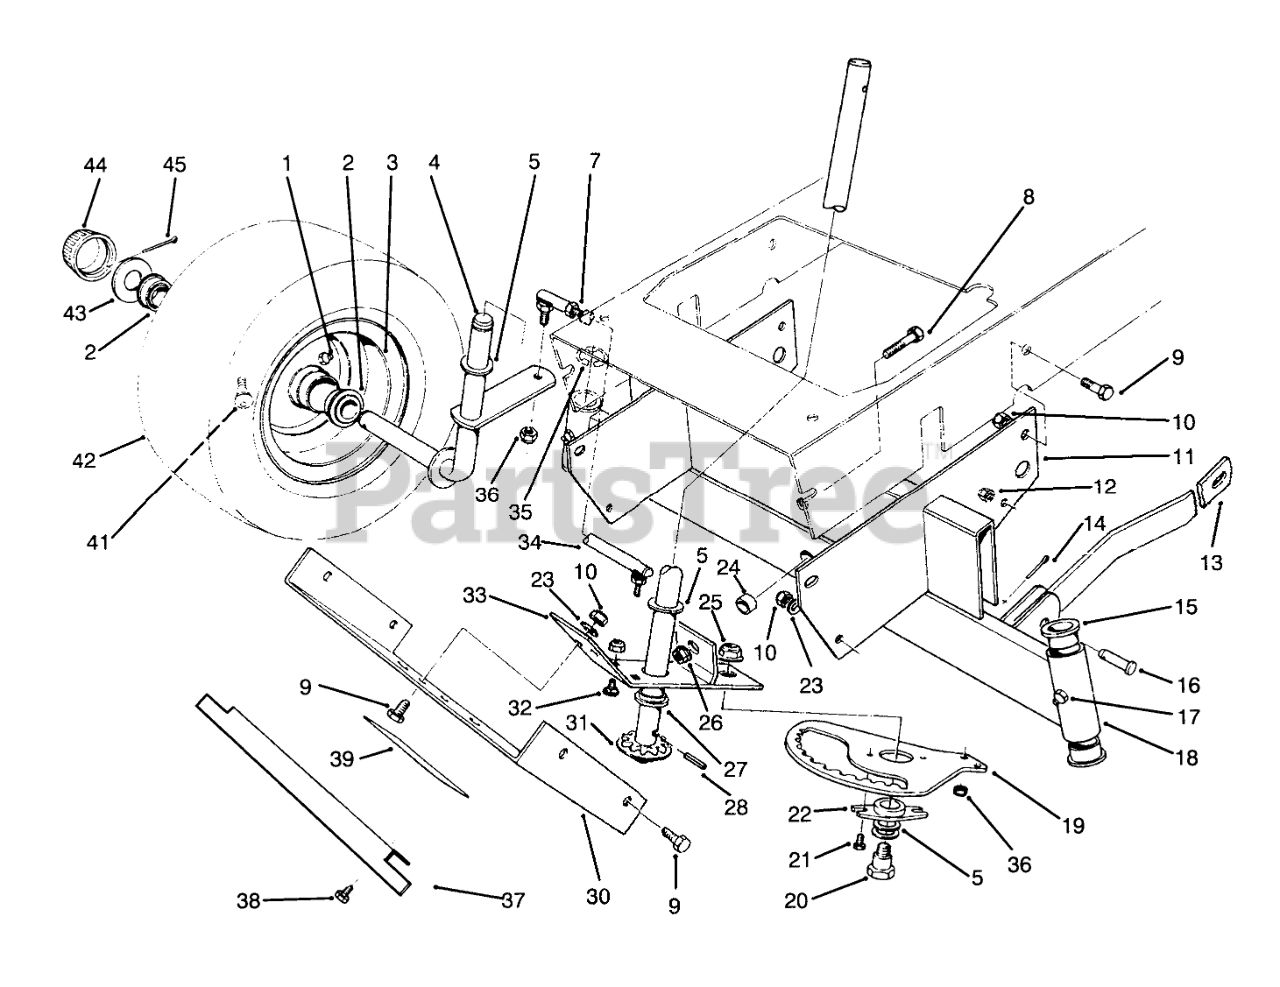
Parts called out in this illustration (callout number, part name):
1	FITTING-GREASE
2	BEARING-WHEEL
4	Spindle RH
5	WASHER-THRUST
7	NUT-JAM
8	SCREW-HH
9	SCREW-HH
10	NUT-LOCK, NI
11	Support
12	NUT-HEX
13	Arm-Suspension, Front
14	PIN-COTTER
15	BEARING-FLANGE
16	PIN-CLEVIS
17	GREASE FITTING
18	Axle-Front (Incl. Ref. #15 & 17)
19	Rack-Steering
21	SCREW-HWH
22	BUSHING-SECTOR
23	WASHER-FLAT
24	SPACER-AXLE, FRONT
25	NUT-HF
26	NUT-HF
27	BEARING-FLANGE
28	PIN-ROLL, SLOTTED
30	Cover-Front
31	STRG SHAFT WA
32	SCREW-CARR
33	Bracket-Rack, Steering (Incl. Ref.#27)
34	Tie Rod-Adjustable (Incl. Ref.#7)
35	E-RING
36	NUT-LOCK
37	Guard-Front
38	SCREW-HWHTF
39	DECAL - IMPORTANT
41	Stem-Valve
42	TIRE,PNEU.11X4.00X5
43	WASHER-PLAIN
44	CAP-HUB
45	PIN-COTTER
